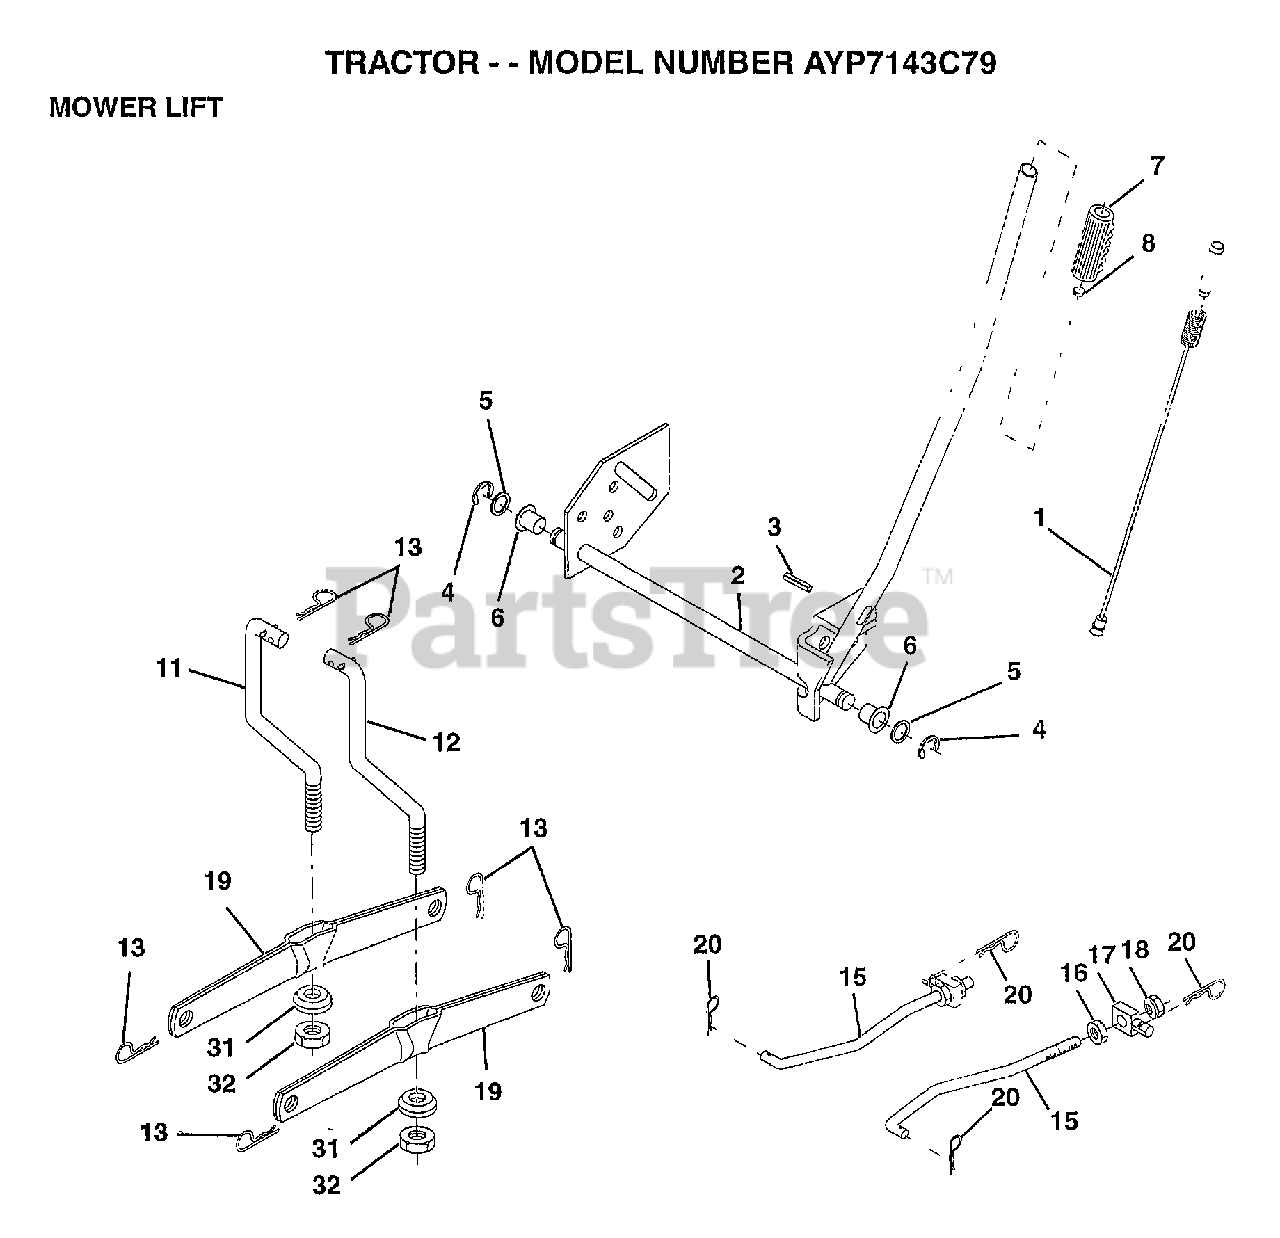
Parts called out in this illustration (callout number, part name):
1	WIRE ASM W.SPRING
2	SHAFT ASM LIFT
3	PIN-GROOVE LT
5	WASHER
6	NYLON BEARING
7	GRIP
15	LINK.FRONT
16	NUT
17	TRUNION
18	NUT.LK.W/WSH.1/2.
19	ARM SUSP REAR
20	RETAINER.SPRING
31	BEARING PVT LH
32	NUT.CROWNLOCK.3/8
